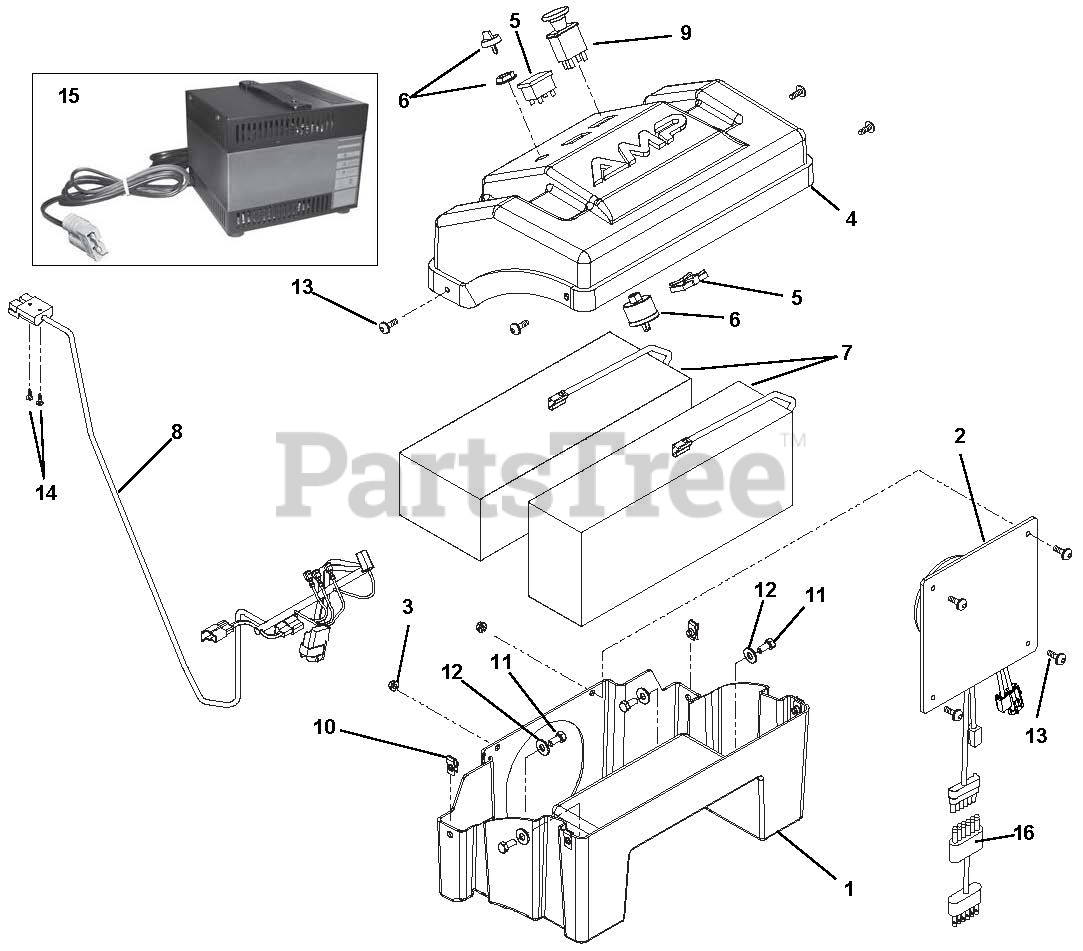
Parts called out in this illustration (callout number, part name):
1	BOX, BOTTOM BATTERY
2	ASSY, DRIVE CONTROLLER
3	@NUT-LK-TOP-FLG .25-20 YWZC
4	COVER, BATTERY BOX-DESIGN 2
5	METER, BATTERY DISCHARGE 48V
6	SWITCH-IGNITION 2-POS W/KEY
8	HARNESS, MAIN ESNOW W/FUSE
9	SWITCH, CLUTCH
10	NUT-RTNR .25-20X.56
11	@BLT-HEX .31-18X.75 GR5 YWZC
12	@WSHR-FL-STL.38X.875X.083 YWZC
13	SCR-SKH.25-20X.62 FLBTNHD G5YZ
14	SCR-TAP 6-32X.75 PH PAN HD
15	CHARGER,BAT.48V5A-TEMP/HIB58.8
15	Charger, Battery
16	HARNESS, MTR/CNTL JUMPER-CE
